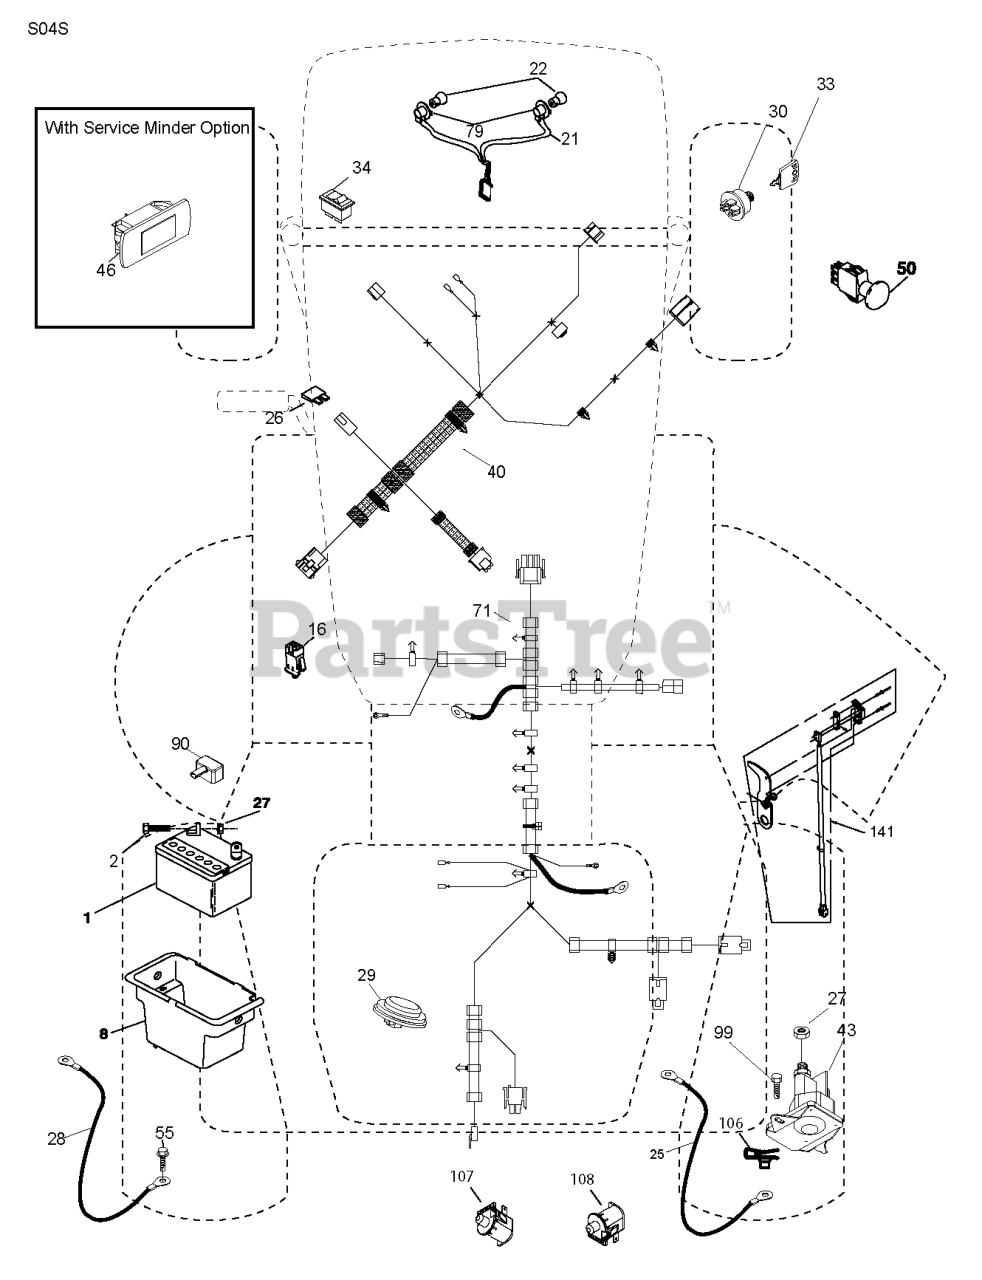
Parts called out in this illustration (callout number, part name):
1	Battery 12 Volt 25 Amp
2	BOLT.HEX.1/4.X.3/4.DICHROMATE
8	BOX.BATTERY.LT/SRD
16	SWITCH INTERLOOK PUSH-IN
21	HARNESS.LIGHT W/4152J BULBS
25	CABLE.BATTERY.20.RED.8 AWG
26	FUSE 20AMP
27	NUT
28	CABLE.GROUND.REAR.BATTERY.8G
29	SWITCH.SEAT.DELTA.OPC.
30	SWITCH.IGN.DELTA.W.LGH.ROS
33	KEY.CHAIN.BLISTER.PACK.GEN.INT
40	WIRING HARNESS
43	SOLENOID.W/BRASS.PLUNGER
46	RP.GUAGE.SRVCMNDR.HRMTR.
50	RP.PTO.SWITCH.8 TERMINAL.BLACK
55	SCREW 5/16"
71	RP.HARNESS.ELEC.CHASSIS.SRD
79	BULB HOLDER ASM.
90	COVER, TERMINAL BATTERY
99	SCREW HEXWSHR 1/4-20X3/4
106	1/4-20 U NUT
107	SWITCH.SNAPMOUNT.NO.#2
108	SWITCH.SNAPMOUNT.NC
141	KIT T2.ROS 71677
